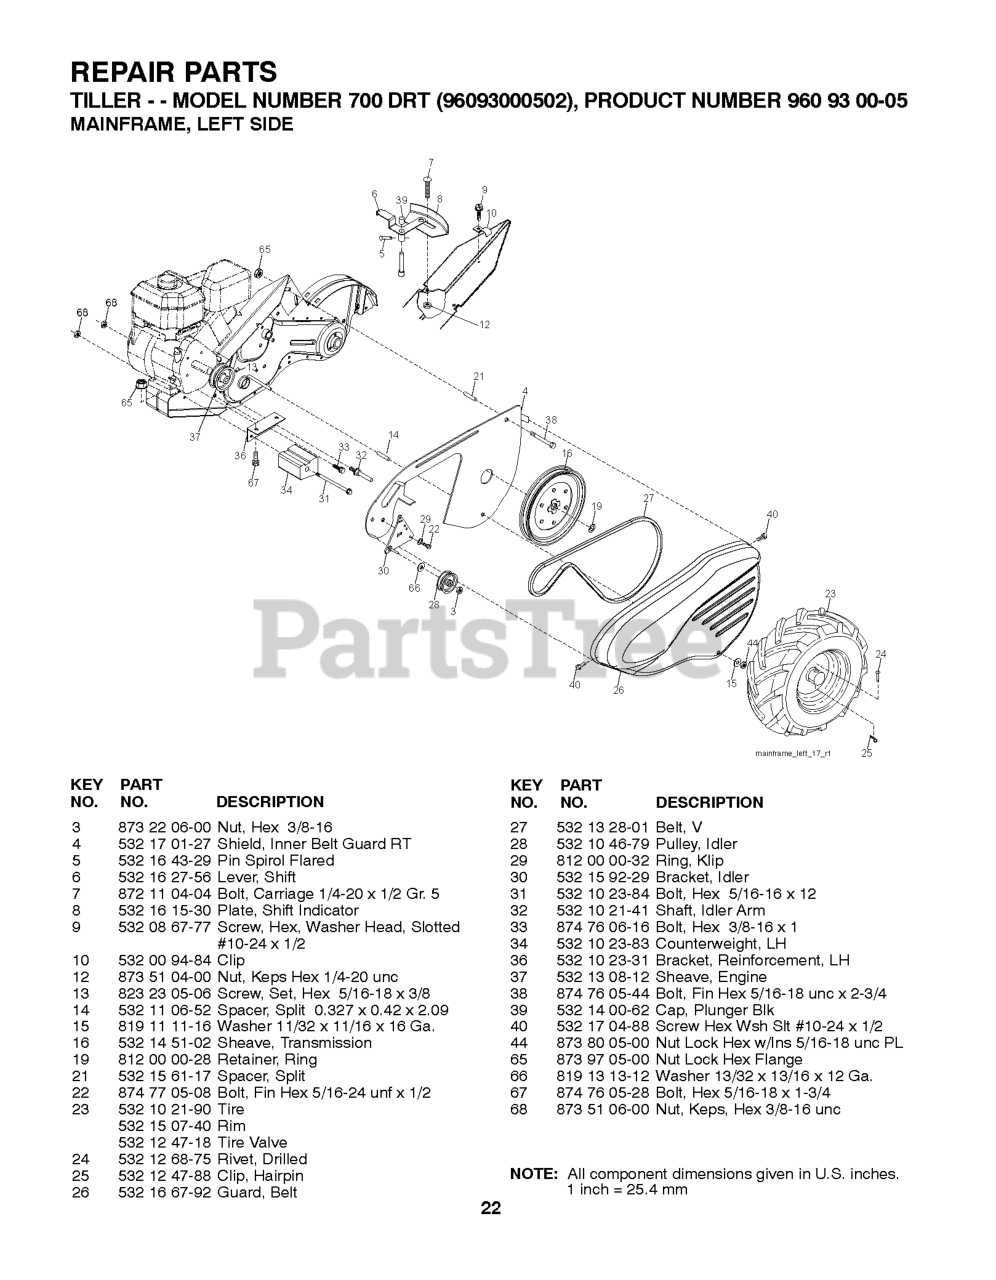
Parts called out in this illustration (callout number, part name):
3	NUT.HEX.3/8-16UNC
4	SHIELD
5	PIN.SPIROL.FLARED
6	LEVER.ASM.SHIFT.RED
8	RP.PANEL.SHIFT
9	TAPPING SCREW
10	CONDUIT.CLIP.PLATED
12	NUT
14	SPACER CRT
15	WASHER
16	SHEAVE, TRANSMISSION
19	RETAINING RING LT
21	SPACER-SPLIT.327 X .42
23	TIRE.13X5-6.CHEVRON.TILLER
24	RIVET,DRILLED
25	RETAINER M
26	RP BELT GUARD
27	V-BELT
28	PULLEY-IDLER TI
30	BRACKET.ASM.IDLER.BLACK
31	BOLT.FIN.HEX.3/8-16UNC
32	SHIFT ARM CRT
33	BOLT
34	COUNTERWEIGHT.LH.CRT
36	BRACKET LH CRT
37	RP.ENGINE PULLEY
38	BOLT
39	CAP.PLUNGER.BLACK
40	SCREW.HEX.WSH.SLT.#10-24X.50
44	NUT.71038.31-18.HEX.NYLOCK
65	LOCKNUT-FLANGE 5/16-18
66	WASHER
67	BOLT, HEX 5/16-18X1-3/4
